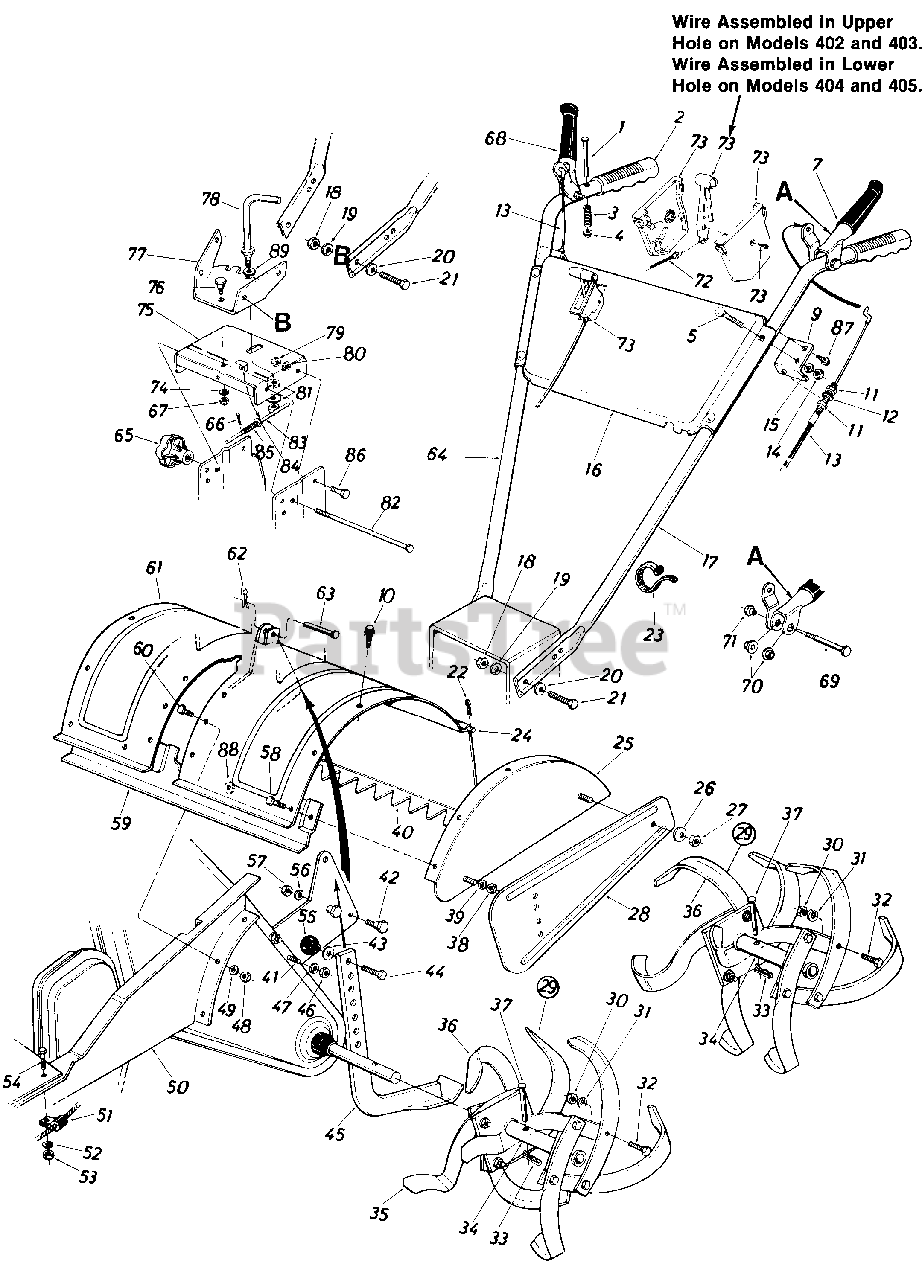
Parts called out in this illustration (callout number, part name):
1	Clevis Pin 1/4" Dia. x 2.25"
2	Grip
3	Compression Spring .33" O.D. x 1.2" Lg.
4	Cap Speed Nut 1/4" Rod
5	Carr. Bolt 5/16-18 x 1.75"
7	Clutch Grip Ass'y.-L.H.
9	Clutch Cable Bracket
10	Hex Wash. S-Tap Scr. 5/16-18 x.62" Lg.
11	Hex Nut 5/16-24 Thd.
12	L-Wash. 5/16" I.D.
13	Clutch Control Cable
14	Hex Nut 5/16-18 Thd.*
15	L-Wash. 5/16" I.D.
16	Handle Panel
17	Handle-L.H.
18	Hex Nut 3/8-16 Thd.
19	L-Wash. 3/8" I.D.
20	Bell-Wash. 3/8" I.D.
21	Hex Bolt 3/8-16 x 1.00" Lg.
22	Cotter Pin 3/32" Dia. x 3/4"
23	Cable Tie
24	Tiller Flap Rod
27	Hex Nut 5/16-18 Thd.
30	Hex Nut 3/8-24 Thd.
31	L-Wash. 3/8" I.D.
32	Hex Bolt 3/8-24 x 1.25" Lg.
33	Hairpin Cotter
38	Hex Nut 5/16-18 Thd.
39	L-Wash. 5/16" I.D.
41	Hex Bolt 5/16-18 x 1.0" Lg.
42	Shld. Bolt 1/2" Dia. x .426"
43	Fl-Wash. 3/8" I.D. x 5/8" O.D.
44	Hex Bolt 3/8-16 x 3/4" Lg.
46	Hex Nut 5/16-18 Thd.
47	L-Wash. 5/16" I.D.
48	Hex Nut 5/16-18 Thd.
49	L-Wash. 5/16" I.D.*
52	L-Wash. 5/16" I.D.
53	Hex Nut 5/16-18 Thd.
54	Hex Bolt 5/16-18 x 3/4" Lg.
55	Ball Knob 1-1/4" Dia.
56	L-Wash. 3/8" I.D.
57	Hex Nut 3/8-16 Thd.
58	Hex Bolt 5/16-18 x .75" Lg.
60	Hex Bolt 5/16-18 x .75" Lg.
62	Hairpin Cotter
63	Clevis Pin 3/8" Dia.
64	Handle-R.H.
66	Cotter Pin 1/16" Dia. x .75" Lg.
67	Hex Cent. L-Nut 3/8-16 Thd.
68	Clutch Grip Ass'y.-R.H.
69	Shoulder Bolt .38" Dia. x 1.53" Lg.
70	Hex Flange Plastic Bearing
71	Shoulder Nut 1/4-20 Thd.
72	Throttle Control Wire
73	Throttle Control Box Ass'y.
74	Bell-Wash. 40" I.D. x 1.13" O.D.
79	Hex Cent. L-Nut 3/8-16 Thd.
80	Bell-Wash. .40" I.D. x .88" O.D.
81	Bell-Wash. 1/2" I.D. x 1.00" O.D.
82	Lock Pin 5/16" Dia. x 8"
83	Lower Sliding Ass'y.
84	Fl-Wash. .291" I.D. x .62" O.D.
85	Compression Spring .36" O.D. x 1.00" Lg.
86	Shoulder Bolt 1/2" Dia. x .170" Lg.
87	Hex Wash. S-Tap Scr. 1/4-20 x.50" Lg.
88	Bell-Wash. 5/16" I.D.
89	Fl-Wash. 5/8" I.D.
